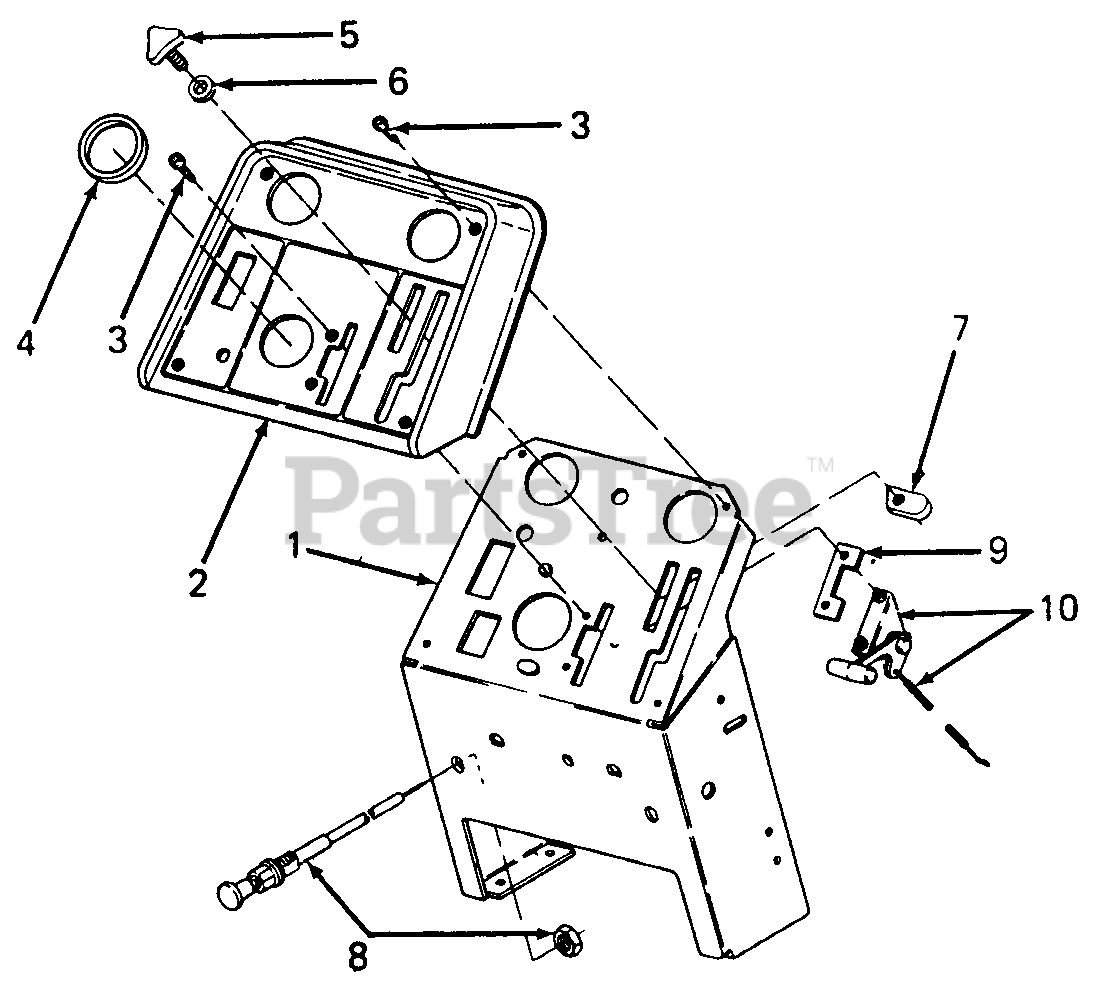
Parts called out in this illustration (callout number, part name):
2	Panel, Instrument
3	Screw, Pan Hd Cutting, #10-24 X .75 Lg
4	Grommet, Instrument Panel
6	Washer, Flat, .266 X .625 X .035 Thk
7	Stop, Detent Handle
8	Choke Cable w/Nut
9	Plate, Throttle Closure
10	Control, Throttle
